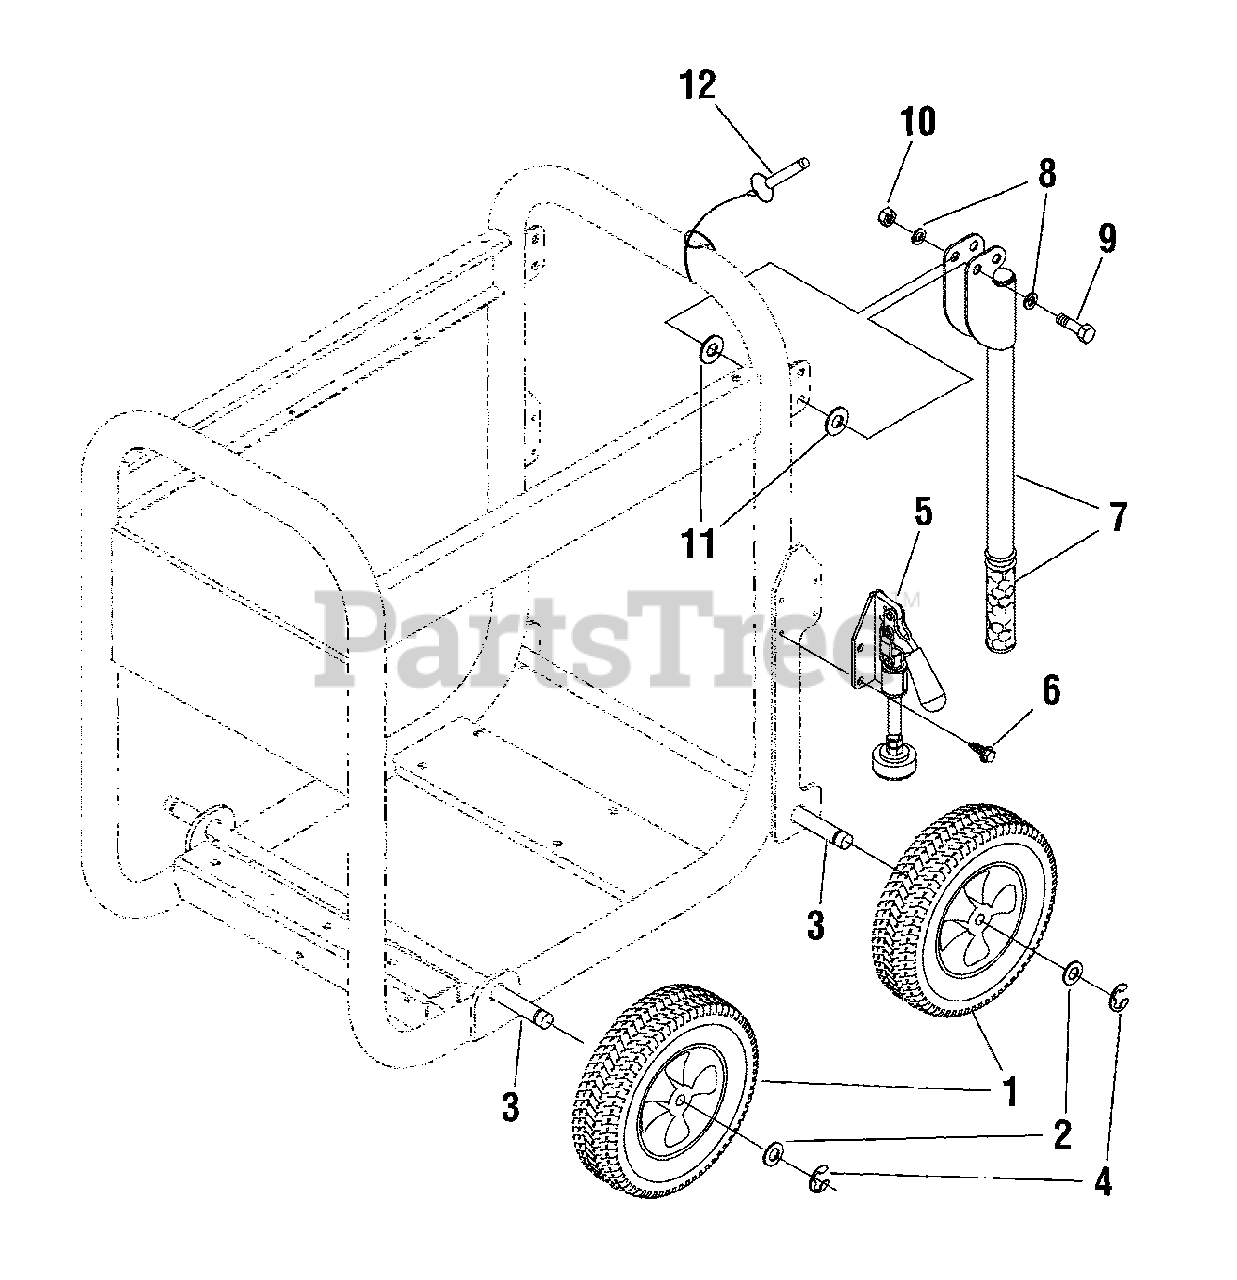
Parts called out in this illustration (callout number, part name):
2	* WASHER, 5/8
4	E-RING
6	* SCREW-1/4-20 x 3/8
7	HANDLE, With Grip
8	* WASHER, Flat, 5/16-M8
9	* NUT, Nylock, M8 - 1-1/4
10	* CAPSCREW, Hex Head, M8 - 1-1/4 x 45
11	* WASHER, Nylon, 1.2 x 0.346 x 0.03
